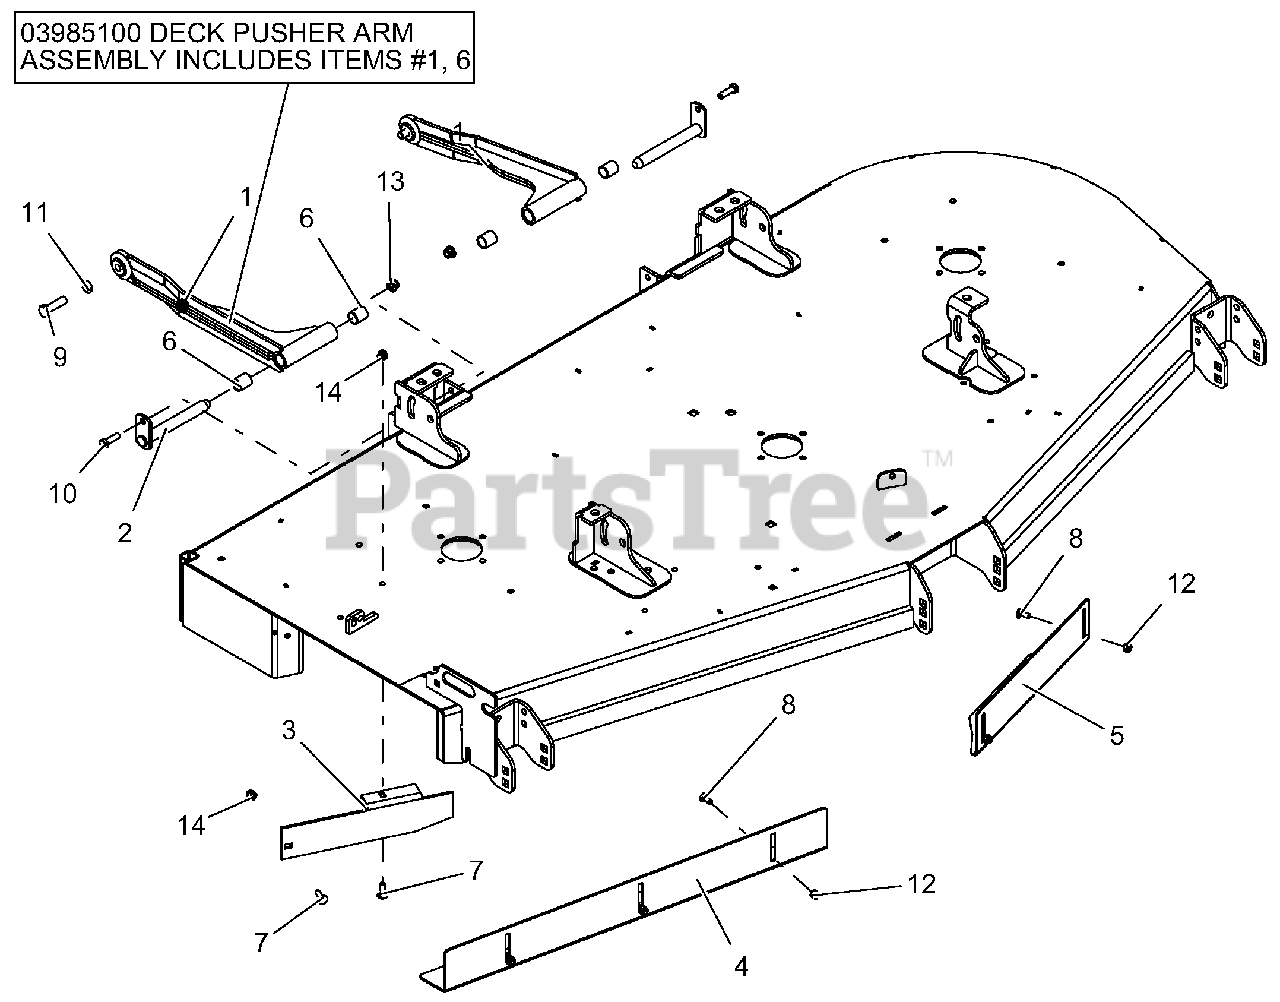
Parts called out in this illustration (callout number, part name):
1	WMT, DECK STABILIZER ARM-BLACK
2	WLDMT, MOWER MTG. PIN
3	BAFFLE, 72" DISCHARGE-RED
4	BAFFLE, 72" RH VACUUM-BLACK
5	BAFFLE, 72" LH VACUUM-BLACK
6	BRG, .75 X .875 X 1.00
7	BLT-RDHDSQSHNK .31-18X1.00 G5 Y
8	BLT-RDHDSQNK .31-18X.75 G5 YWZC
9	BLT-HEX .50-13X1.75 GR5 YWZC EP80
10	BLT-HEX .38-16X1.25 GR5 YWZC
11	WSHR-LK .50X.125 REG YWZC
12	NUT-LK-NYL .312-18 YWZC
13	NUT-LK-NYL-FLG .38-16 YWZC
14	NUT-LK-NYL-FLG .31-18 YWZC
